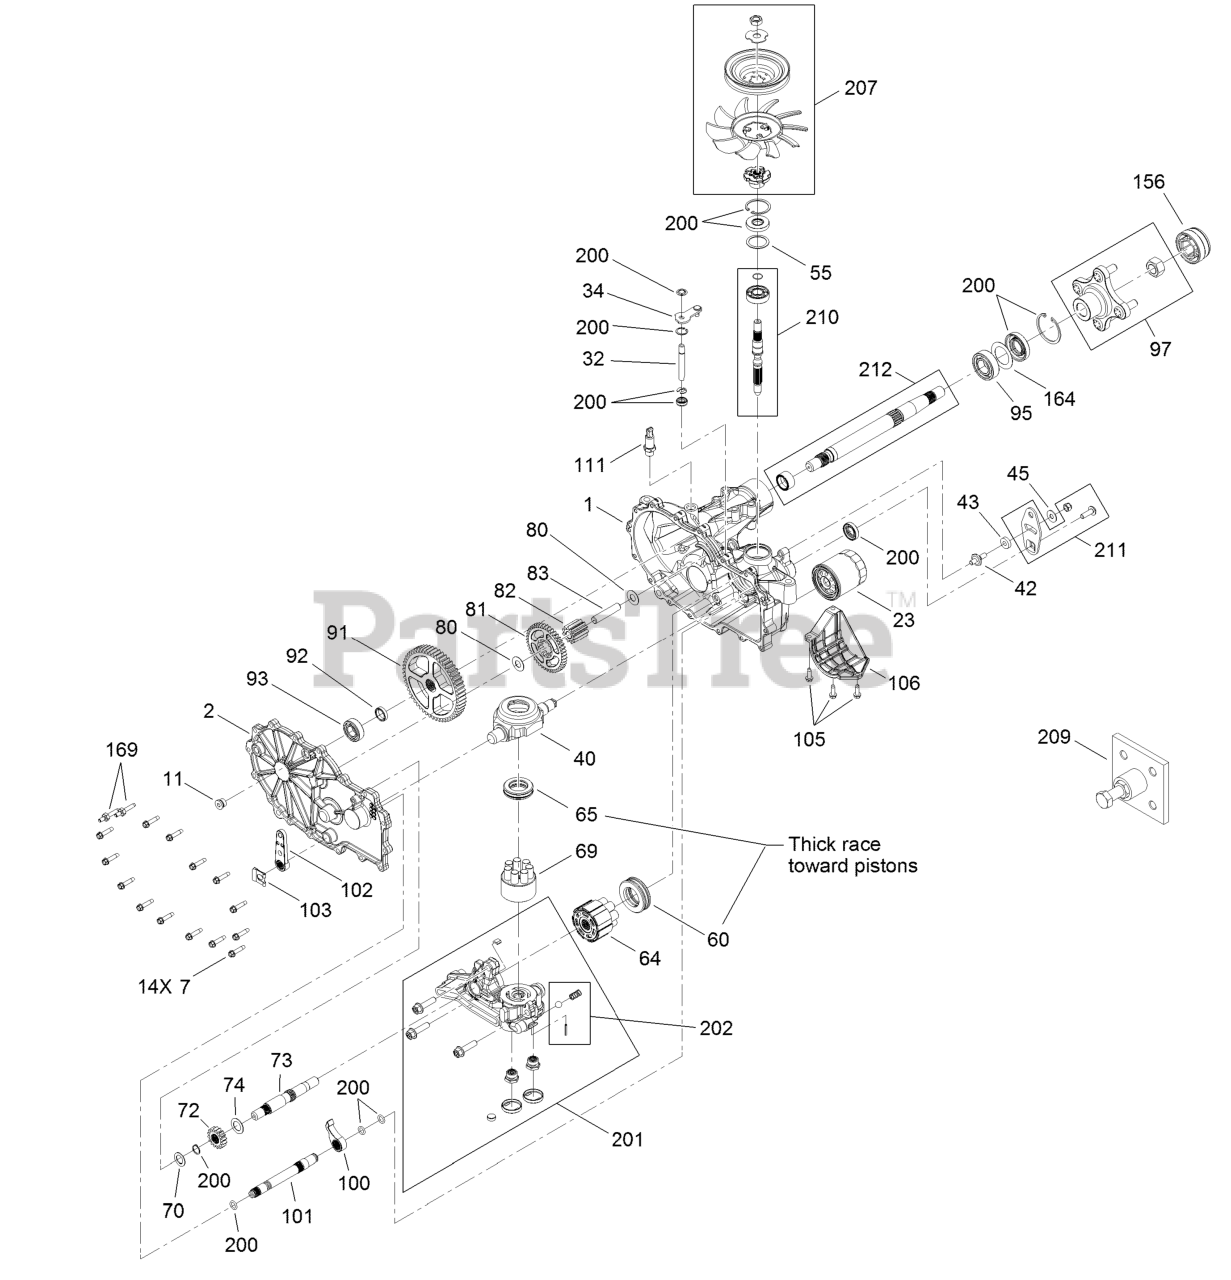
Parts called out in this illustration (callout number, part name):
1	MAIN HOUSING KIT
2	LH SIDE COVER KIT
7	SCREW-HHF
11	PLUG-THREAD, STRAIGHT
23	ELEMENT-OIL FILTER, HYD
32	ROD-BYPASS
34	ARM-BYPASS
40	SWASHPLATE-TRUNNION
43	PUCK-FRICTION
60	BEARING-THRUST
64	MOTOR CYLINDER BLOCK KIT
65	BEARING-THRUST
69	PUMP BLOCK ASM
70	WASHER-FLAT
72	GEAR-16T
73	SHAFT-MOTOR
81	GEAR-43T
82	GEAR-11T
83	PIN-JACKSHAFT
91	GEAR-54T
93	BEARING-BALL
95	BEARING-BALL
97	HUB KIT
100	PAWL-BRAKE
101	SHAFT-BRAKE, INBOARD
102	HANDLE-BRAKE
103	CLIP-RETAINING
106	GUARD-FILTER, LH
111	ADAPTER-STRAIGHT
156	COVER-NUT, AXLE
200	SEAL KIT
201	CENTER SECTION KIT
202	CHARGE RELIEF KIT
207	FAN PULLEY KIT
210	INPUT SHAFT KIT
211	CONTROL ARM KIT
212	AXLE SHAFT KIT
